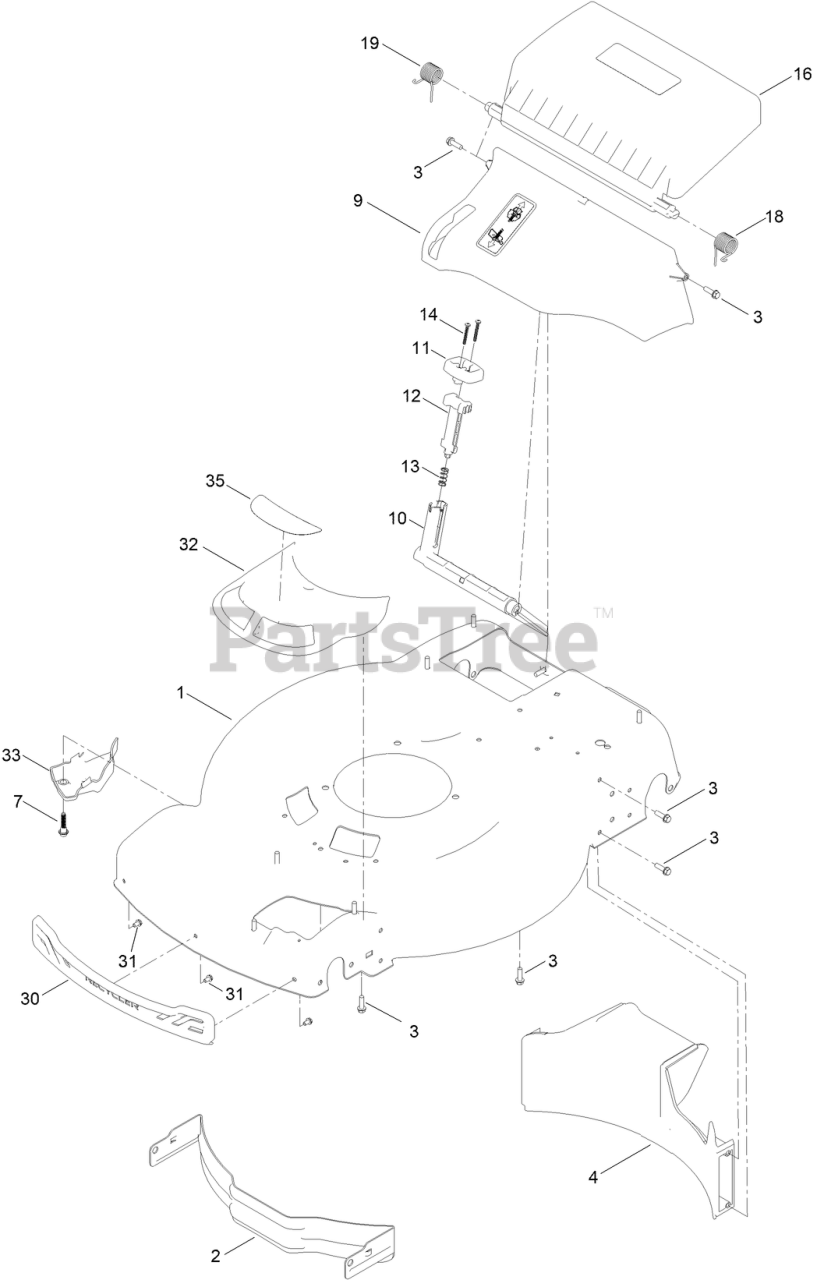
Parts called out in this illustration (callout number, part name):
1	HOUSING ASM
2	BAFFLE-FRONT
3	SCREW-PLASTITE, HWH
4	BAFFLE-REAR, RWD
7	SCREW-SHOULDER, HHF
9	ASM-CHUTE, IN MOLD
10	DEFLECTOR-RECYCLE
11	KNOB-RECYCLE
12	LATCH-RECYCLE
13	SPRING-COMPRESSION
14	SCREW-PPH
16	ASM-REAR DOOR, IN MOLD
18	SPRING-TORSION, LH
19	SPRING-TORSION, RH
30	BUMPER-FRONT
31	SCREW-PLASTIC, HWH
32	ASM-INTAKE, RWD
33	COVER-INTAKE, BOTTOM
35	DECAL-VORTEX RWD
